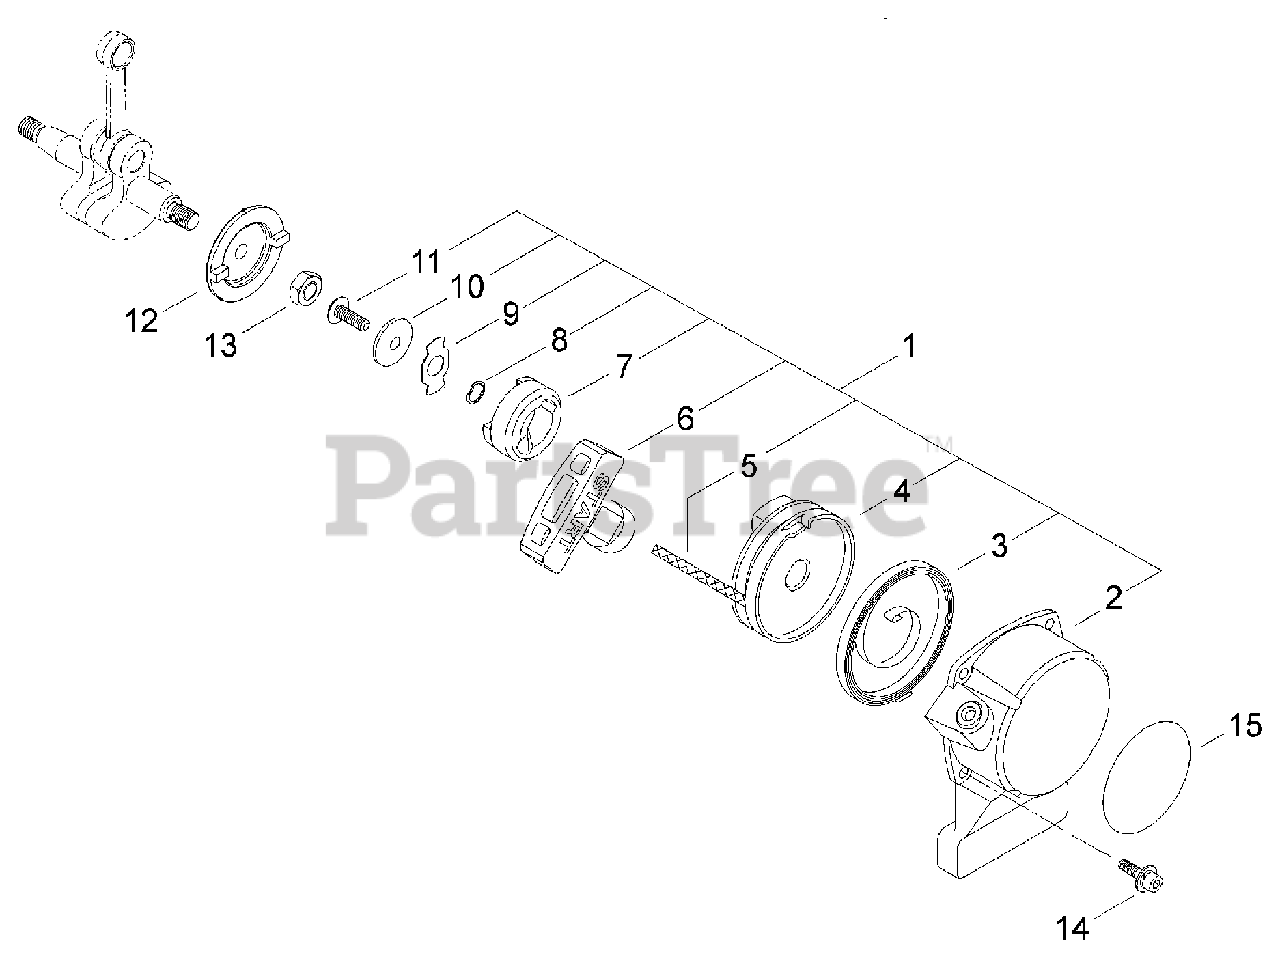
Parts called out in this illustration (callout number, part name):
1	STARTER ASSY, RECOIL
2	CASE, RECOIL STARTER
3	SPRING, RECOIL
4	REEL, ROPE
5	ROPE, STARTER
6	GRIP, STARTER
7	PAWL, STARTER
8	WASHER, WAVE
9	RETAINER
10	WASHER 5 MM
11	SCREW 5 MM
12	PULLEY, STARTER
13	NUT M8×1
14	BOLT M4×16
15	LABEL, SWISHER E4
